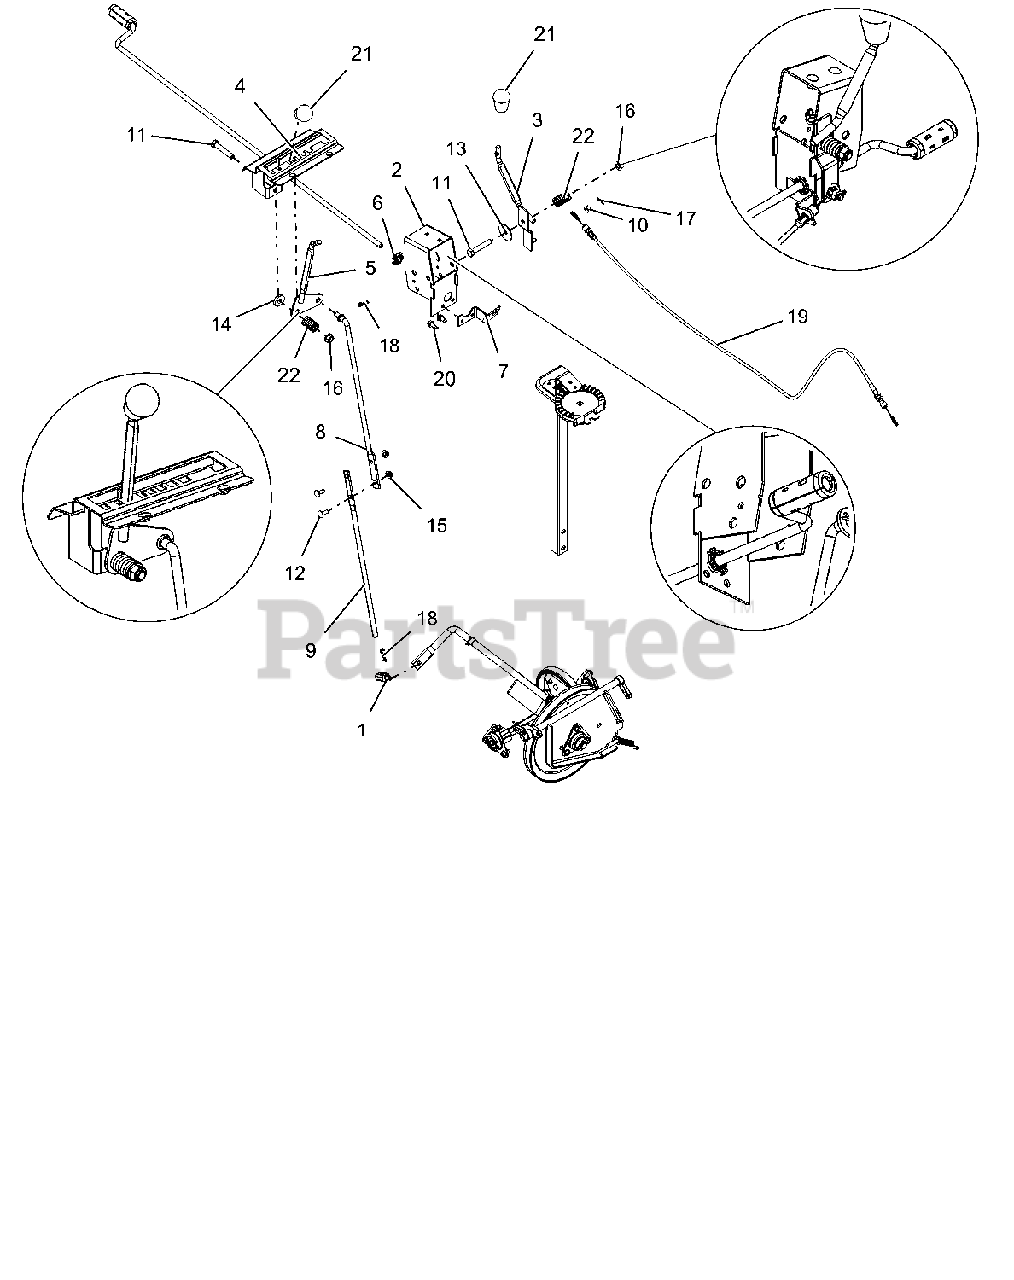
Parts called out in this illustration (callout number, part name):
1	PIVOT,SHIFT ROD .375-16(TRUNN)
2	WELDMENT, BRACKET INTERLOCK
3	WELDMENT,SM DASH DEFL CONTROL
4	WELDMENT, DETENT PLATE-COMPACT
5	LEVER, CONTROL-SHIFT(WELDMENT)
6	CRANK BUSHING, NYLON CHUTE BK
7	ANCHOR, DEFLECTOR CABLE
8	ROD, SHIFT - UPPER
9	ROD, SHIFT - LOWER
10	BSHG-SLV .265X.500X.219
11	@BLT-HEX .38-16X2.00 GR5 YWZC
12	@BLT-RDHDSQNK .25-20X.75 G5YZ
13	WSHR-FL-STL .380X1.50X.062 YWZ
14	WSHR-FL-STL .406X1.00X.188 YWZ
15	@NUT-LK-CTR-FLG .25-20 YWZC
16	@NUT-LK-TOP-FLG .38-16 YWZC
17	PIN-HAIR INT .06X.18X.77
18	PIN-HAIR INT .08X.18X1.18 YWZC
19	CABLE, DEFLECTOR CAP SNO-TEK
20	SCR-TAP .25-20X.50 HWH TR YWZ
21	KNOB,SOFT TEARDROP,PUSH-ON BLK
22	SG-COMP .125X.781X1.250
